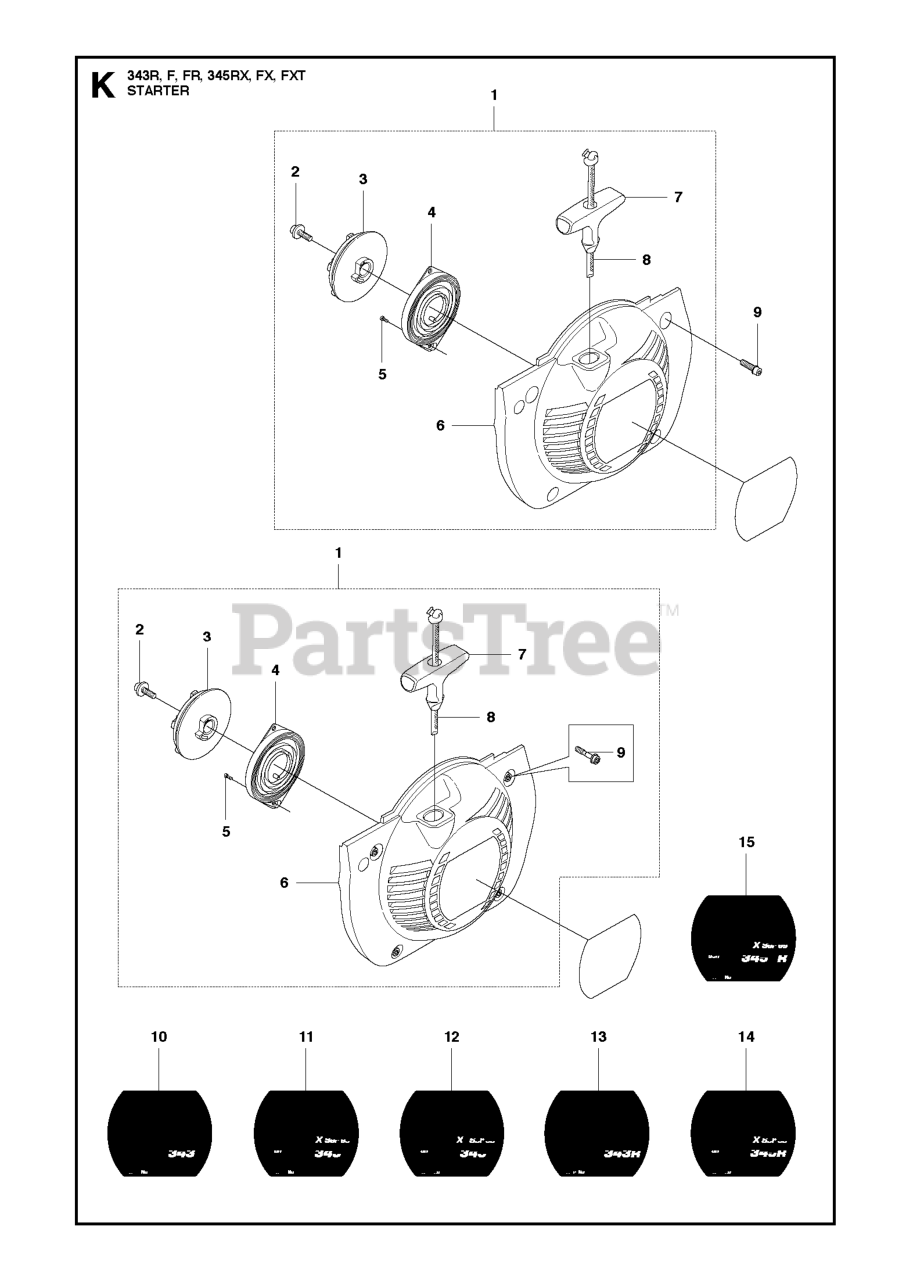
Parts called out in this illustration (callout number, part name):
1	STARTER ASSY.
1	STARTER ASSY
3	STARTER PULLEY
4	RECOIL SPRING
6	STARTER DEVICE
7	STARTER HANDLE
8	STARTER ROPE
9	SCREW IHSCFM
9	SCREW IHSCFMO
10	LABEL STARTAP.343F
11	DECAL
12	LABEL STARTAP.345FXT
13	LABEL STARTAP.343R
14	DECAL
15	LABEL STARTAP.343FR
